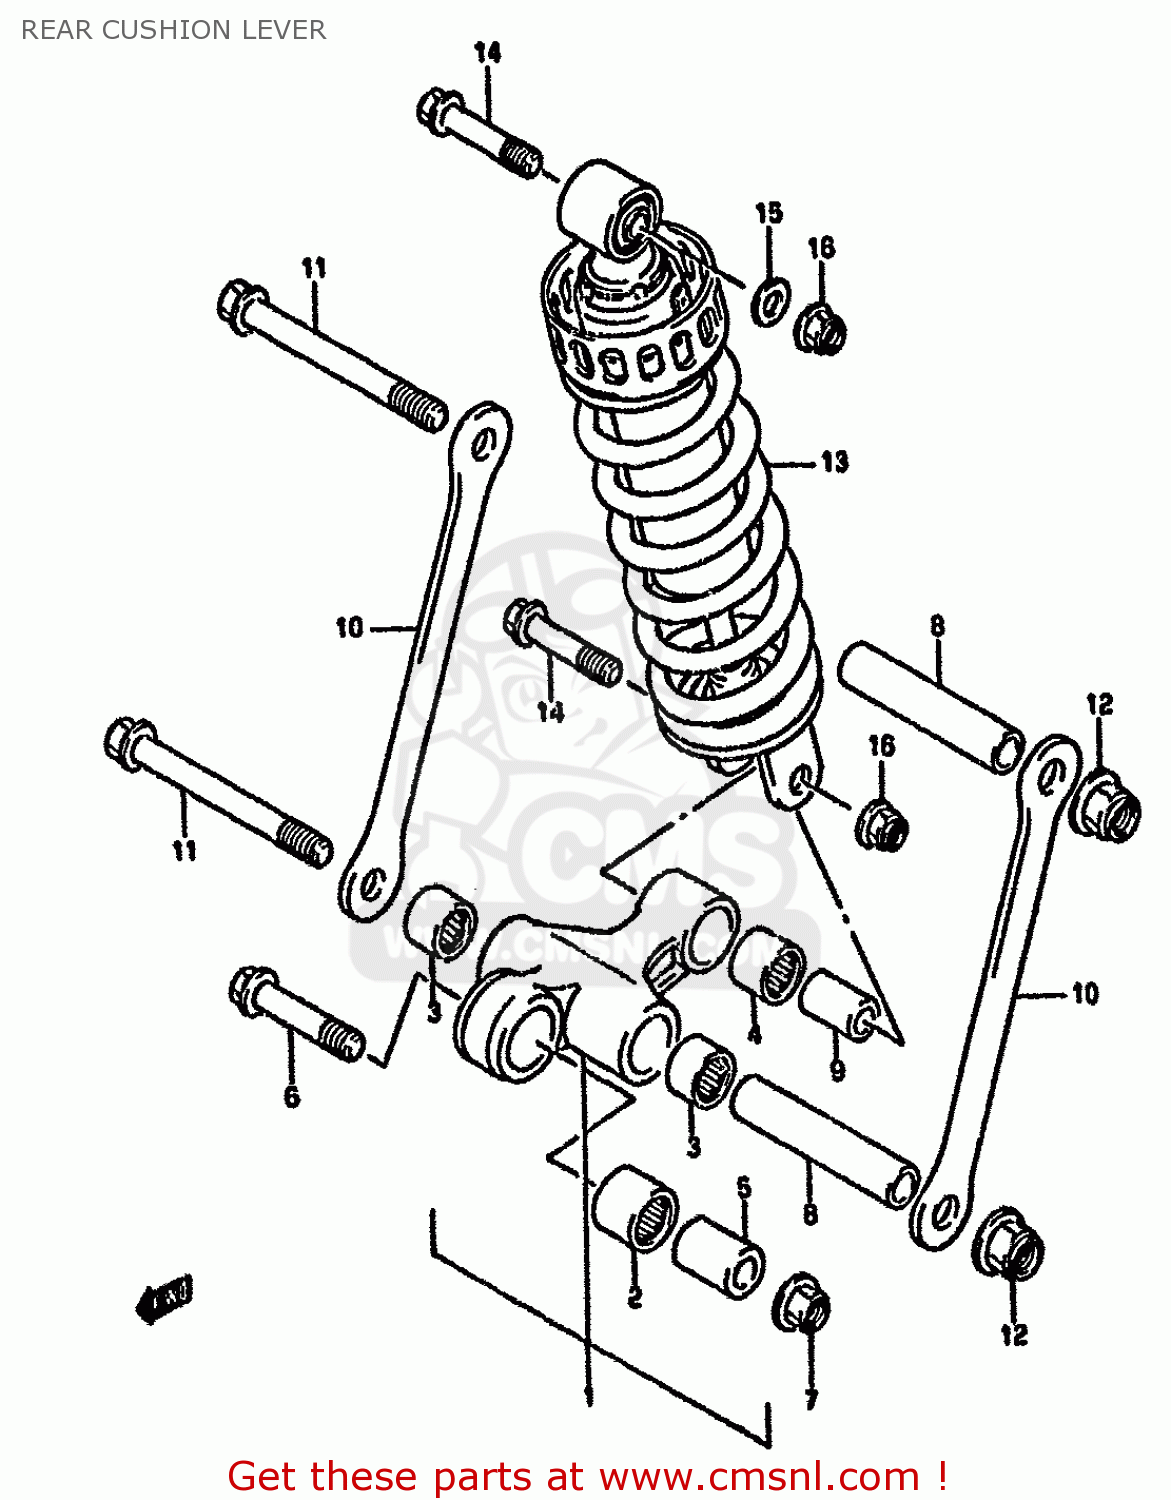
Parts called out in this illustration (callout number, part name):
1	LEVER SET,RR CUSHION
2	BEARING(20X27X26)
3	BEARING(17X24X25)
4	BEARING(17X24X26)
5	SPACER,REAR CUSHION LEVER
6	BOLT
7	NUT 12MM
8	SPACER(12X17X85)
9	SPACER,RR CUSHION LEVER
10	ROD,RR CUSHION LEVER
11	BOLT(12X115)
12	NUT 12MM
13	ABSORBER ASSY,REAR SHOCK
14	BOLT(10X52)
15	WASHER 10MM
16	NUT 10MM
